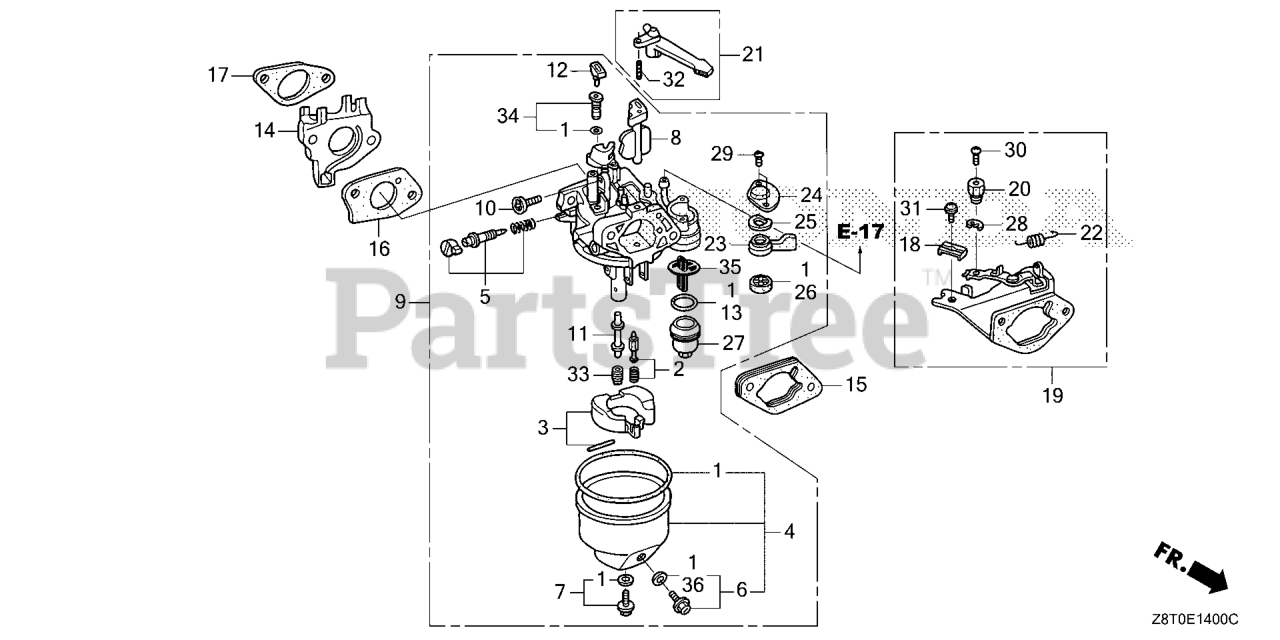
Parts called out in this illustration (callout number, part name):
1	GASKET SET (INCLUDE 16173-001-004) (INCLUDES 16173-001-004)
2	VALVE SET, FLOAT
3	FLOAT SET
4	CHAMBER SET, FLOAT
5	SCREW SET (Honda Code 4219879). (CARBURETOR NO.)
6	SCREW SET, DRAIN
7	SCREW SET (CARBURETOR NO.)
8	CHOKE SET
9	CARBURETOR ASSY. (BE80Z A)
10	SCREW, THROTTLE STOP
11	NOZZLE, MAIN
12	COLLAR, SET
13	GASKET, FUEL STRAINER CUP
14	INSULATOR, CARBURETOR
15	SPACER, CARBURETOR
16	GASKET, CARBURETOR
17	GASKET, CARBURETOR INSULATOR
21	LEVER, CHOKE (STD)
23	LEVER, VALVE
24	PLATE, LEVER SETTING (CARBURETOR NO.)
25	SPRING, PETCOCK LEVER (CARBURETOR NO.)
26	GASKET, VALVE
27	CUP, FUEL STRAINER
29	SCREW, PAN (3X6)
32	PIN, SPRING (2X12)
33	JET, MAIN (#92)
33	JET, MAIN (#95)
33	JET, MAIN (#100) Use from Engine SN BE87A A to BE87A A.
34	JET SET, PILOT (#40) (ADVENTURE GREEN) (CARBURETOR NO.)
35	FILTER, CUP (CARBURETOR NO.)
36	WASHER, PLAIN (6.2X10.7 DRAIN) (CARBURETOR NO.)
